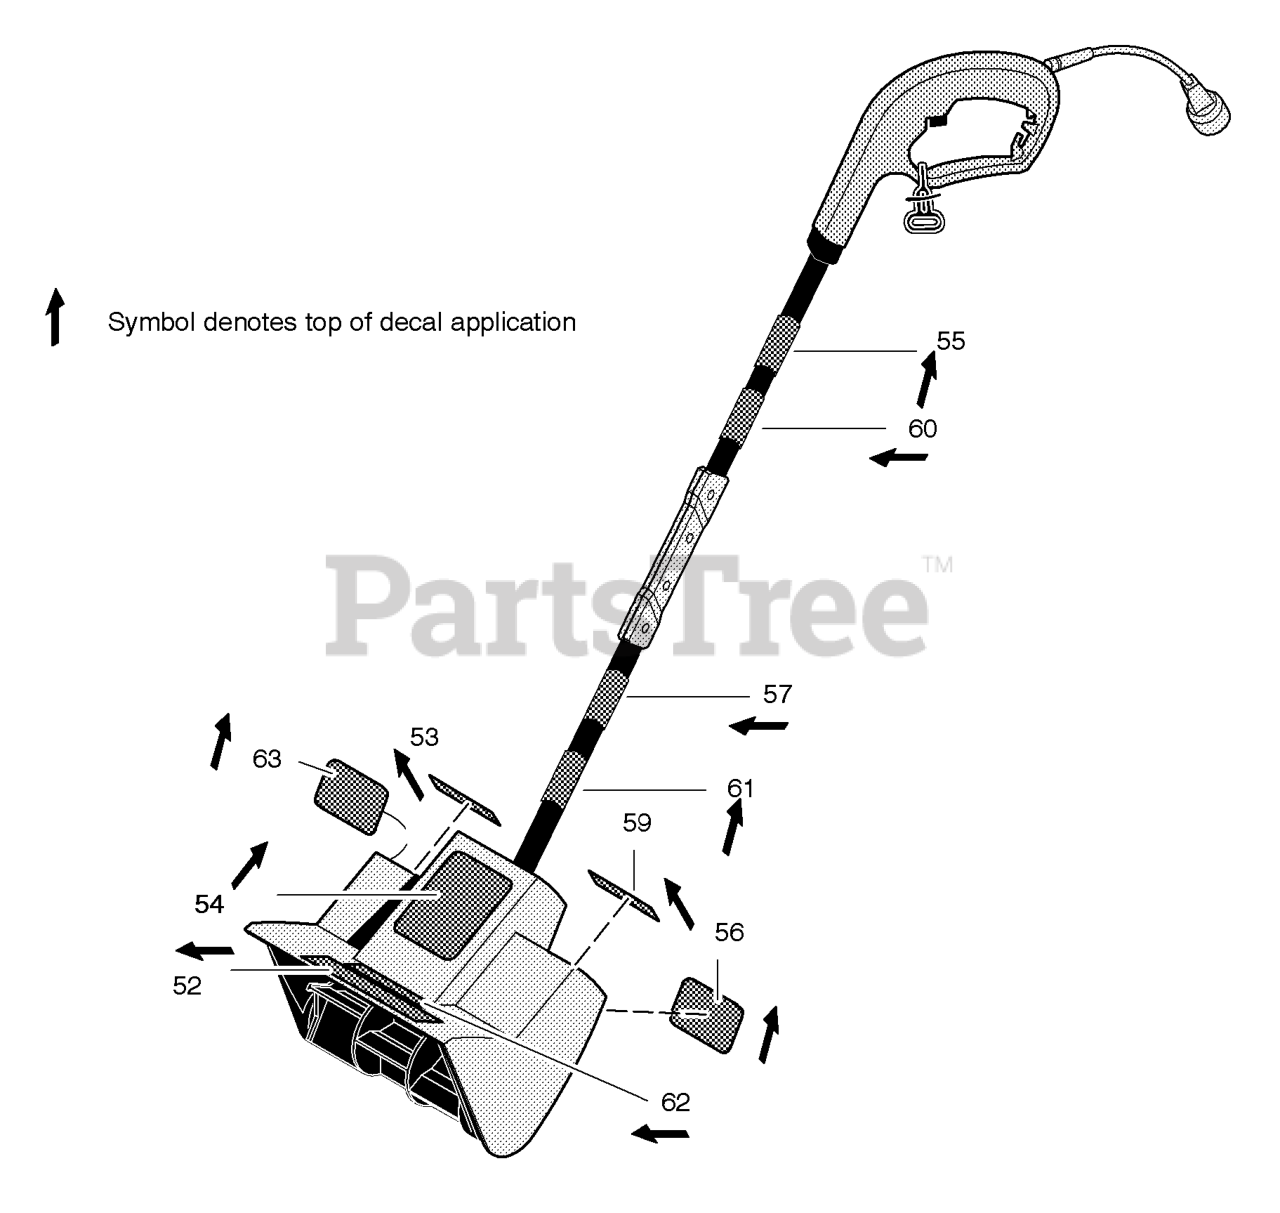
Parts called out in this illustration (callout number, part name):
52	Decal, Danger Foot
53	Decal, Caution E12
54	Decal, Murray
55	Decal, Cord Usage 12/14"
56	Model Name Plate
57	Decal, Pinched Wire
59	Decal, Caution
60	Decal, Motor Protection
61	Decal, Motor Protection
62	Decal, Warning
63	Decal, Caution Rain
